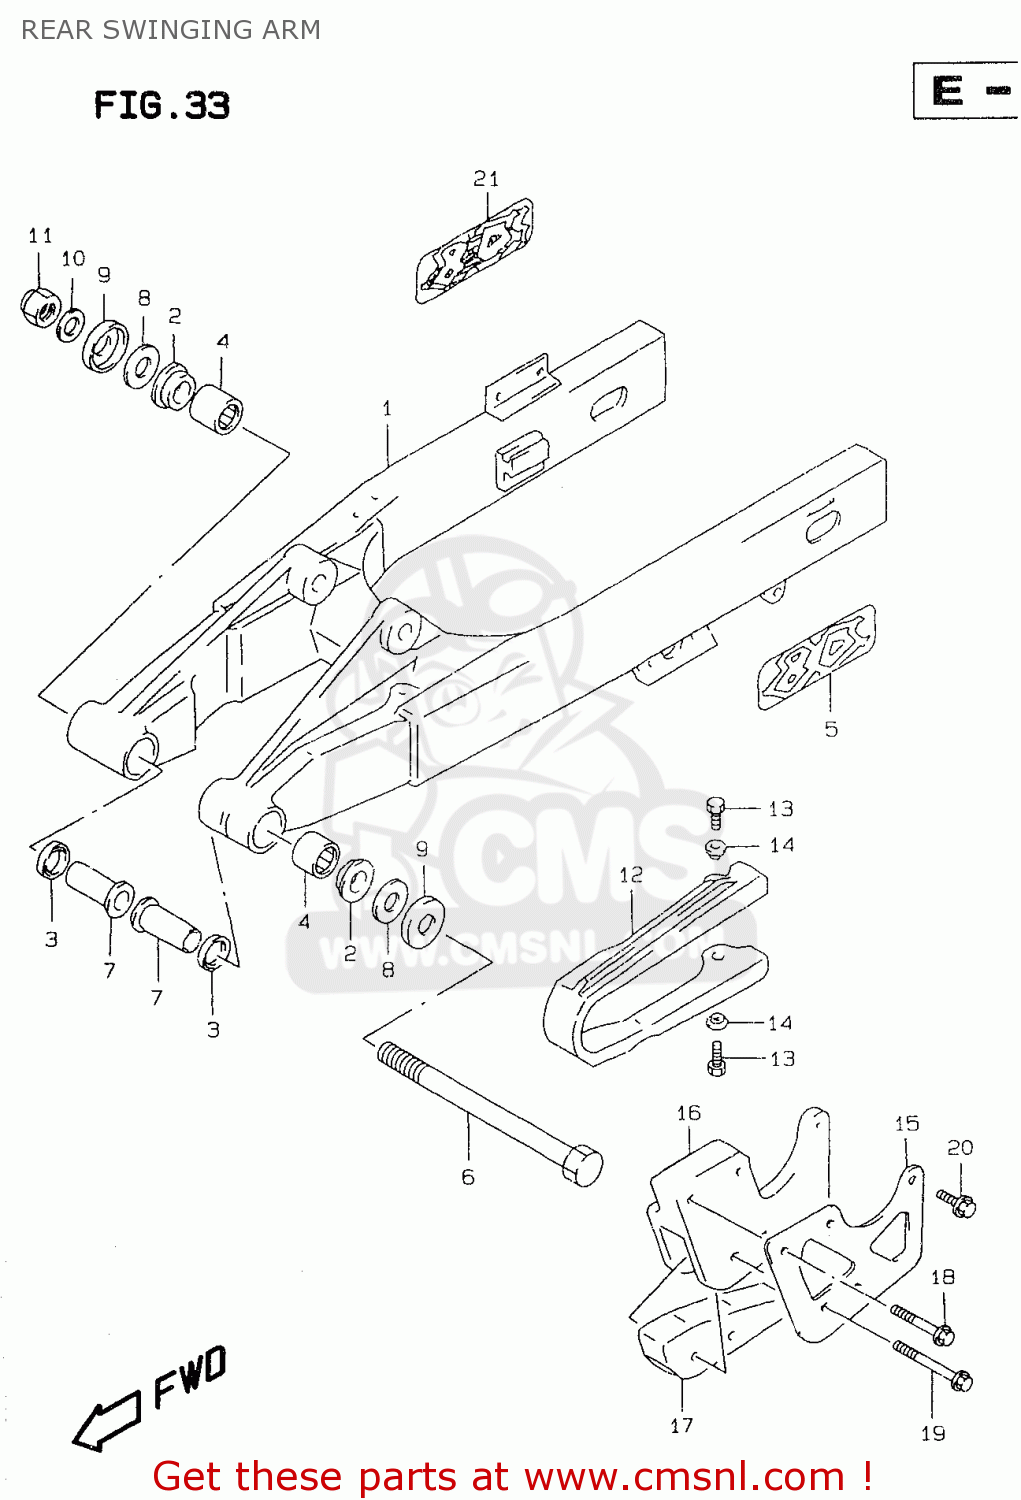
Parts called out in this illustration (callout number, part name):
1	SWINGINGARM ASSY,RR
2	BUSHING,SWGARM PIVOT
3	SEAL,OIL(17X24X3)
4	BEARING(17X24X30)
5	EMBLEM,SWING ARM
6	SHAFT,RR SWINGINGARM PIVOT
7	SPACER,RR SWGARM PIVOT
8	WASHER
9	COVER,SWGARM PIVOT
10	WASHER
11	NUT 12MM
12	BUFFER,CHAIN TOUCH DEFENSE
13	BOLT
14	WASHER
15	PLATE,GUIDE CHAIN OUTER
16	GUIDE,CHAIN
17	DEFENSE,CHAIN GUIDE
18	BOLT,G/S SWITC
19	BOLT
20	BOLT
21	EMBLEM,SWINGINGARM
